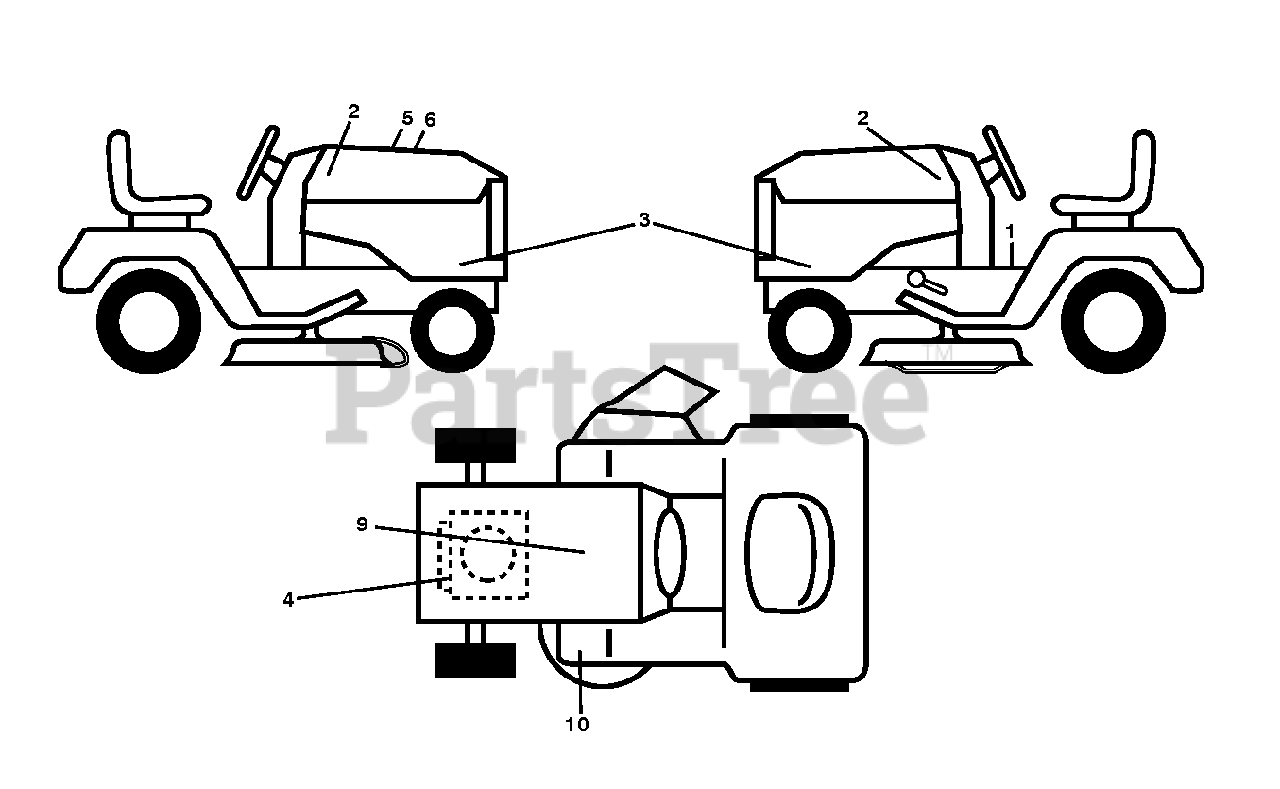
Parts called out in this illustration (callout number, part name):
1	DECAL.FENDER.WARNING
2	RP.DECAL.BADGE.170MM.TEXTLOGO
3	DECAL.SDPNL.HUSQGT2.YTH22V42LS
4	DECAL, ENG. HP
5	DECAL.WARNING.CUST.RESP.E85.
6	Decal, Replacement BSM4O ENDR TLB 42F K
9	DECAL BTRY SYMBOLS
10	DECAL.PEDAL.HUSQ.CROWN
